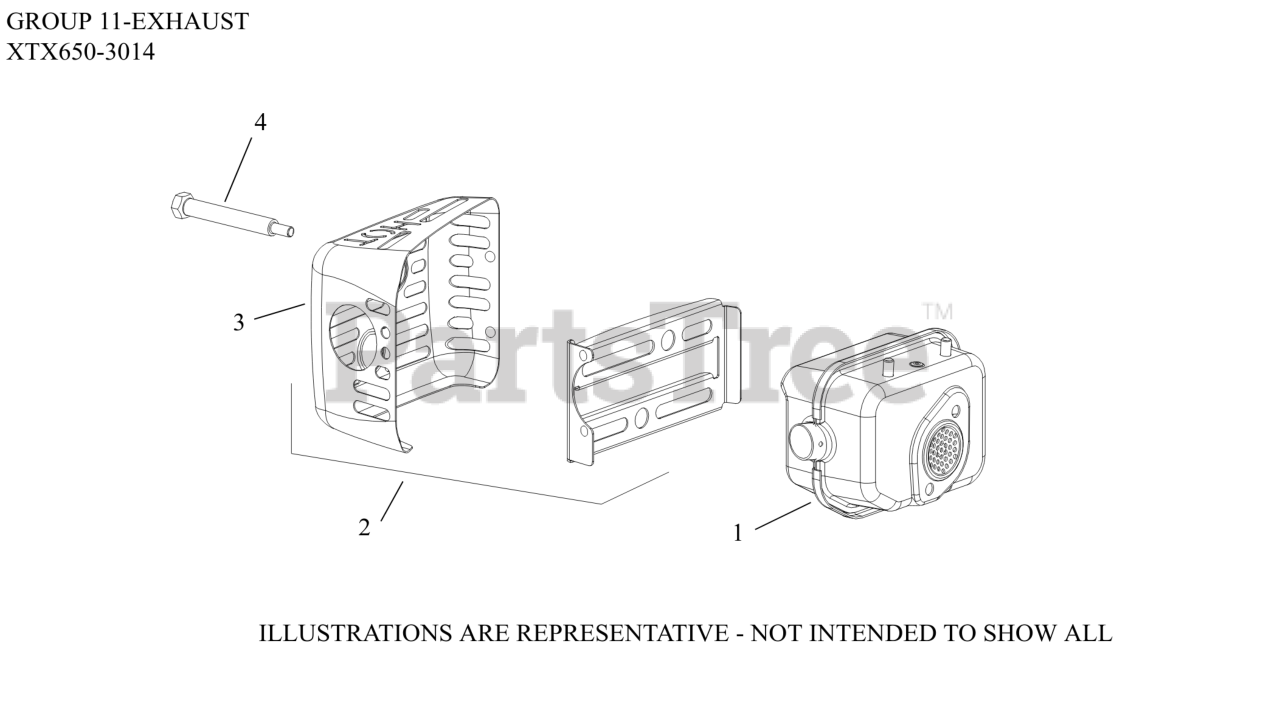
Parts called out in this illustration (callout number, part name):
1	MUFFLER, ASSEMBLY
2	GUARD, MUFFLER ASSEMBLY
3	GUARD, MUFFLER - DISCONTINUED
4	SCREW, SHOULDER
